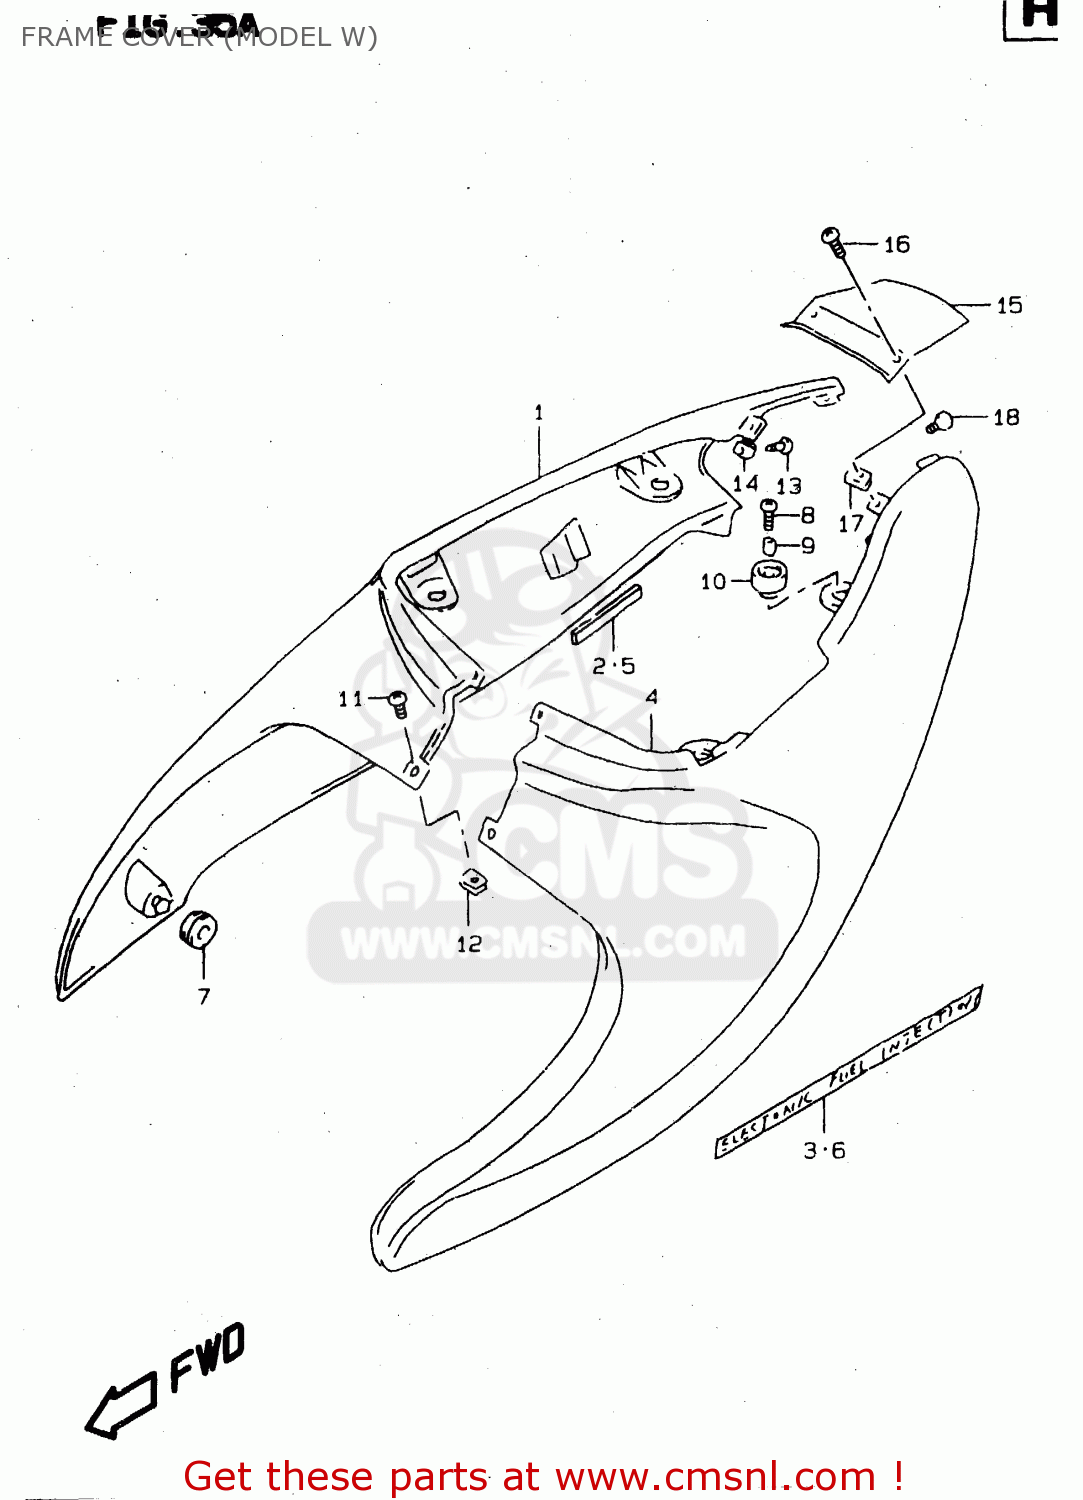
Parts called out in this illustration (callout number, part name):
1	COVER,FRAME,R(RED)
2	CUSHION,FRAME COVER
3	EMBLEM,FRAME COVER
4	COVER,FRAME,L(RED)
5	CUSHION,FRAME COVER
6	EMBLEM,FRAME COVER
7	CUSHION
8	SCREW(6X20)
9	SPACER(6.5X10X9.4)
10	CUSHION
11	SCREW
12	NUT
13	SCREW(5X16)
14	NUT
15	COVER,FRAME CTR
16	SCREW
17	NUT
18	CUSHION
